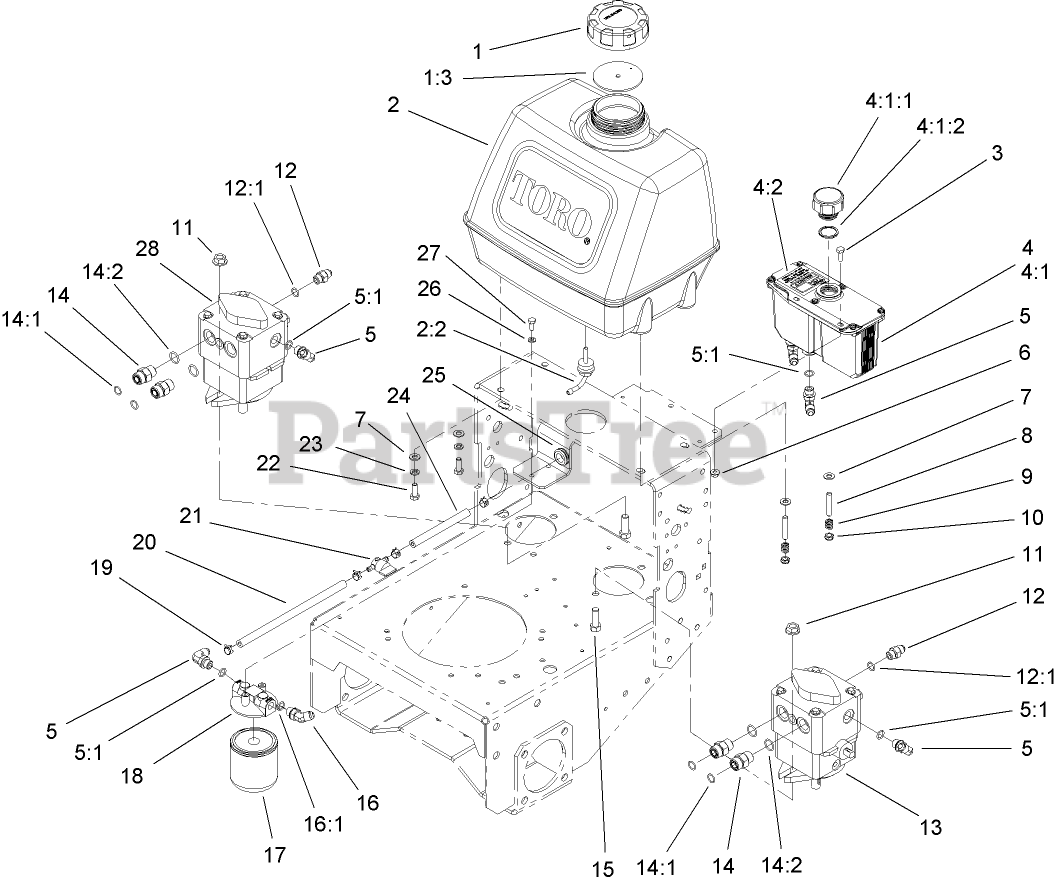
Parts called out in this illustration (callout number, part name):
1	GAS CAP ASM
1:3	GASKET-CAP, GAS
2	FUEL TANK ASM
2:2	FITTING-FUEL, BULKHEAD
3	SCREW-HH
4	HYD Reservoir ASM
4:1	Reservoir-HYD
4:1:1	CAP-RESERVOIR, HYD
4:1:2	GASKET-CAP
4:2	DECAL-TANK, HYD
5	FITTING-ELBOW, 90 DEG
5:1	O-RING
6	NUT-HF
7	WASHER-PLAIN
8	STUD-THREADED
9	SPRING-TANK, FUEL
10	NUT-LOCK, NI
11	NUT-HF
12	FITTING-STRAIGHT
12:1	O-RING
13	HYDRAULIC PUMP ASM
14	FITTING-STRAIGHT
14:1	O-RING
14:2	O-RING
15	SCREW-HH
16	FITTING-ELBOW, 45 DEG
16:1	O-RING
17	FILTER-OIL, HYD (WINTER)
17	FILTER-OIL, HYD
18	HEAD-FILTER
19	CLAMP-HOSE
20	HOSE-FUEL
21	VALVE-FUEL
22	SCREW-HH
23	WASHER-LOCK
24	HOSE-FUEL
25	GROMMET
26	WASHER-LOCK
27	SCREW-HH
28	HYDRAULIC PUMP ASM
